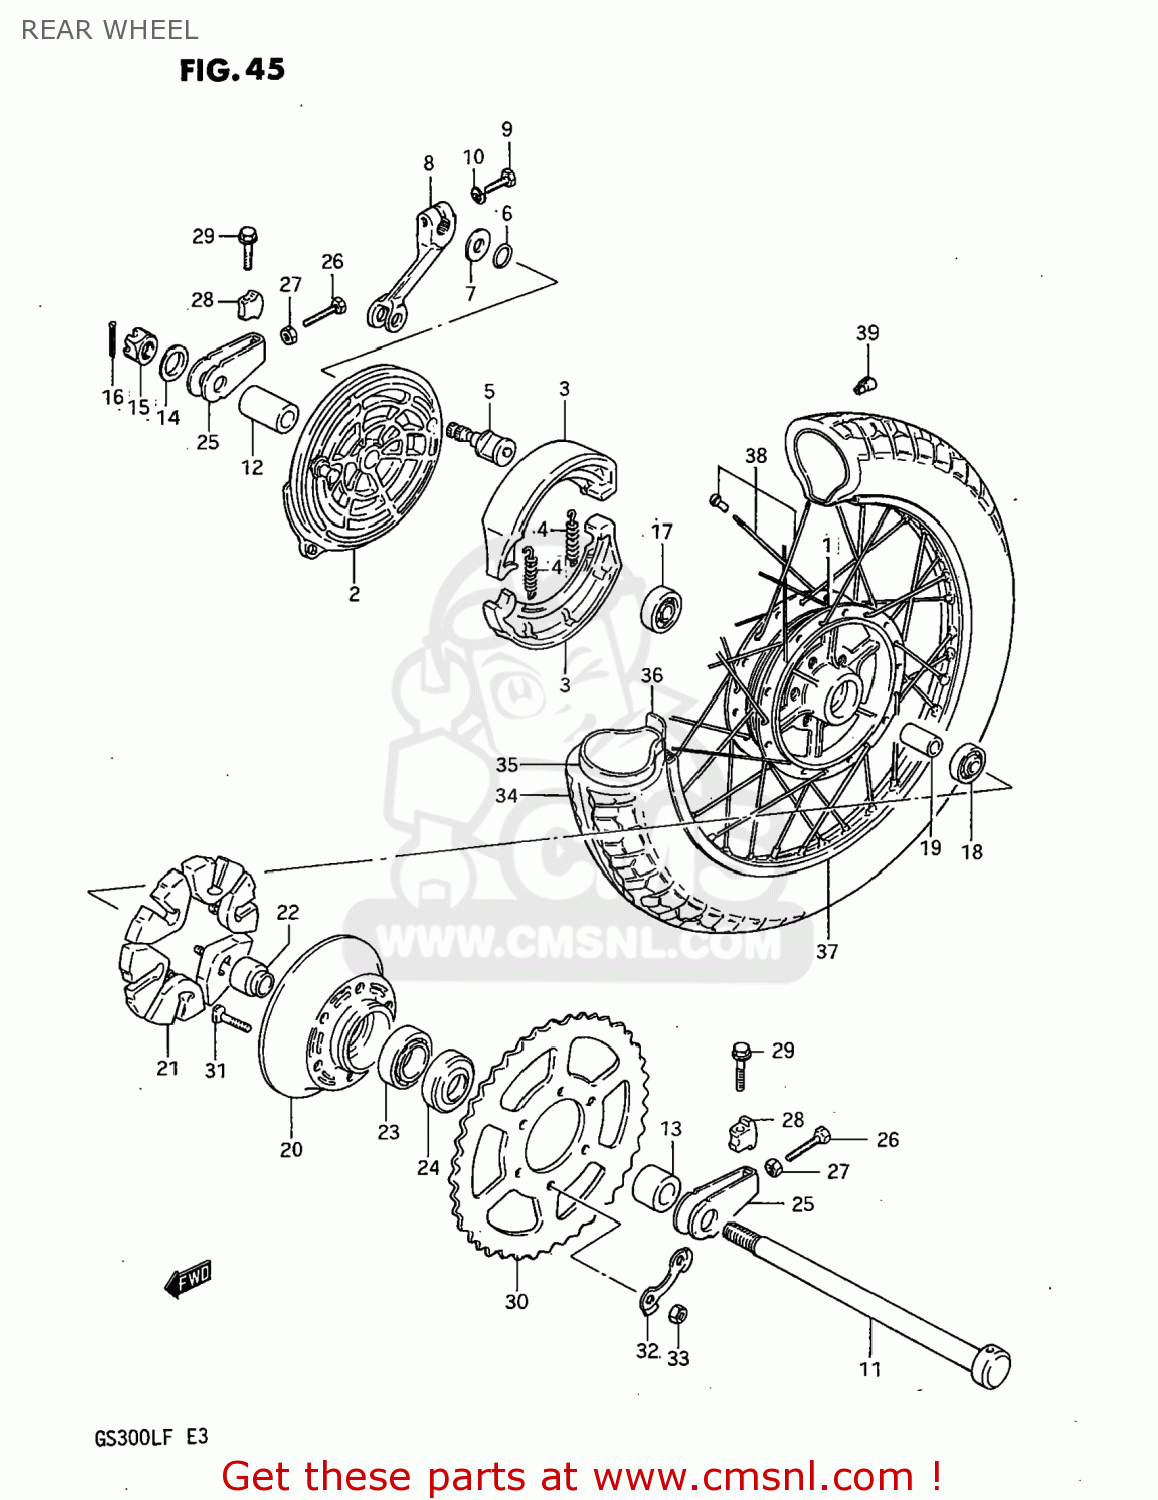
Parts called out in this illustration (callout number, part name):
1	DRUM,REAR HUB
2	PANEL,REAR HUB
3	SHOE,BRAKE
4	SPRING,BRAKE SHOE
5	CAM,FRONT BRAKE
6	O-RING,BOSS
7	WASHER (15X24X1.6)
8	LEVER,RR BRAKE CAM
9	BOLT
10	LOCK WASHER
11	AXLE,REAR
12	SPACER(17.5X28X44.8)
13	SPACER(17X30.5X22.3)
14	WASHER (17X30X3.2)
15	NUT
16	PIN,COTTER
17	BEARING
18	BEARING
19	SPACER (17.6X24X57)
20	DRUM,REAR SPROCKET MOUNT
21	ABSORBER,RR HUB SHOCK
22	SPACER,REAR HUB BEARING
23	BEARING
24	SEAL,OIL(30.5X52X8)
25	ADJUSTER,CHAIN
26	BOLT 8X50
27	NUT
28	SUPPORTER,CHAIN ADJUST
29	BOLT, UPPER
30	SPROCKET,REAR (NT:42)
31	BOLT 10X33
32	WASHER
33	NUT
34	TIRE
35	TUBE ASSY,WHEEL,INNER 4.60-16
36	PROTECTOR,INNER TUBE
37	RIM,REAR WHEEL
38	SPOKE SET,REAR WHEEL
39	BALANCER,WHEEL (B)
